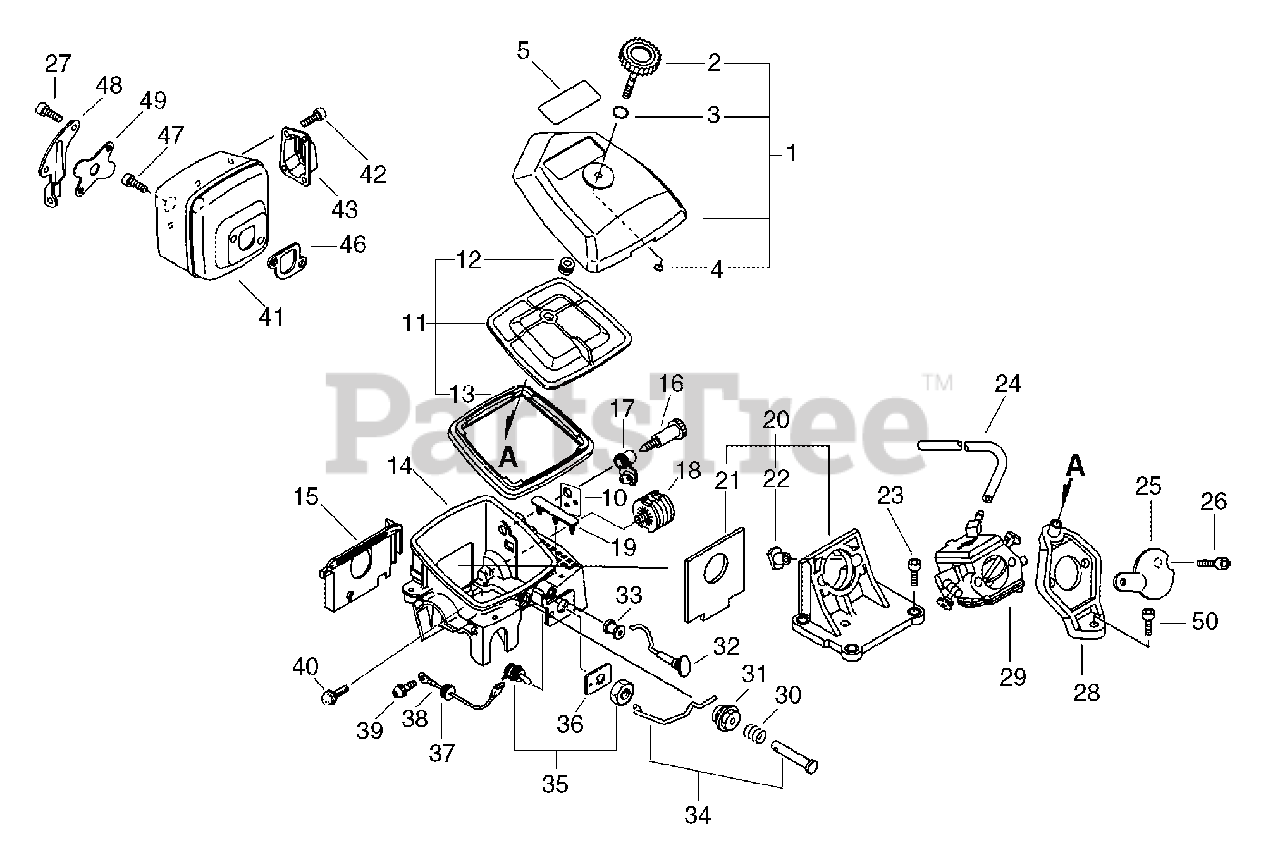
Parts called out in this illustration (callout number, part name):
1	COVER ASSY, AIR FILTER
2	THUMBSCREW
3	O-RING 10
4	O-RING 3
5	LABEL, MODEL
10	LABEL, ADJUSTING
11	FILTER ASSY, AIR
13	SEAL, AIR FILTER
14	CASE, CARBURETOR - ORANGE
15	PLATE, GUIDE
16	SCREW, IDLE ADJUST - ORANGE
17	GROMMET, NEEDLE
19	PLUG
20	INSULATOR
21	SEAL, DUST
22	NUT
23	BOLT 5×25
24	PIPE, IMPULSE 3×6(8)×160
26	BOLT 5×55
27	BOLT 5×14
28	BRACKET, AIR FILTER
29	CARBURETOR - HDA-153B
31	GROMMET, THROTTLE ROD
32	ROD, CHOKE - ORANGE
33	GROMMET, CHOKE
34	ROD, THROTTLE
35	SWITCH, ON-OFF
36	LABEL, STOP
39	SCREW 4×8
40	SCREW 4×8
42	BOLT 4×10
43	COVER, MUFFLER
46	GASKET, MUFFLER
47	BOLT 6×20
48	BRACKET, MUFFLER
49	COVER, MUFFLER
50	BOLT 5×20
